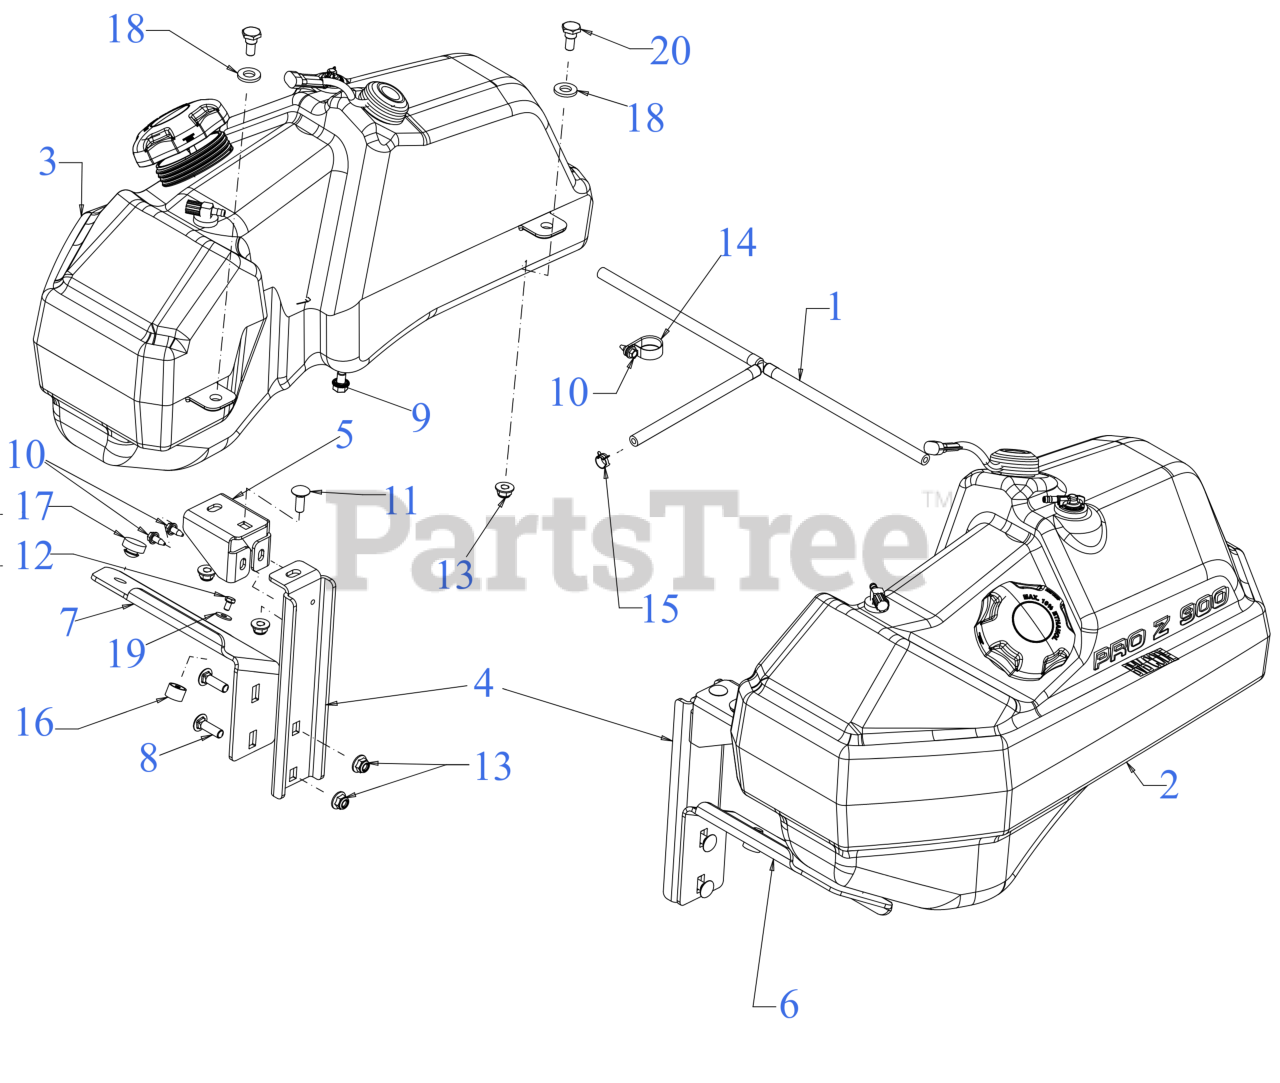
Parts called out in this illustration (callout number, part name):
1	FUEL LINE ASSEMBLY
2	FUEL TANK ASSEMBLY (RH) (7.25 GAL)
3	FUEL TANK ASSEMBLY (LH) (7.25 GAL)
4	FUEL TANK MOUNTING BRACKET
5	FUEL TANK MOUNTING BRACKET
6	LOWER FUEL TANK BRACKET (RH)
7	LOWER FUEL TANK BRACKET (LH)
8	CARRIAGE BOLT 3/8-16 X1.25 GR5
9	SCREW 3/8-16 x .500 GR5
10	SCREW 1/4-20X.625
11	CARRIAGE BOLT 3/8-16 x 1.00 GR5
12	SCREW M6-1.0X10MM GR8.8
14	DRAIN HOSE CLAMP
17	RUBBER BUMPER 1.000 x .313
18	FLAT WASHER .510 x 1.000 x .125
19	FLAT WASHER
20	SHOULDER SCREW .498 DIA x .340
